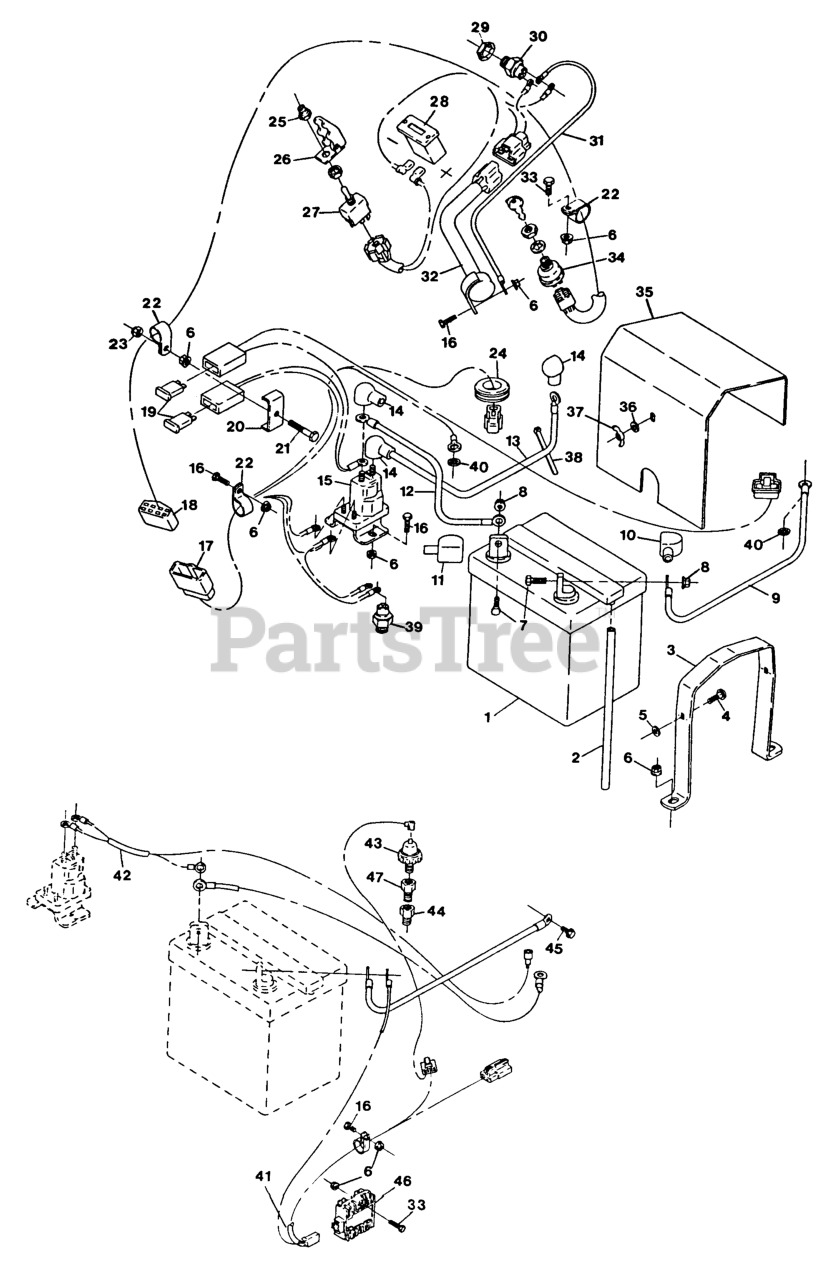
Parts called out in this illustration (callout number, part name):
1	Battery, 12v Manifold
3	STRAP,BATTERY HOLDDOWN
4	BOLT-CARR
5	NUT-RETAINING
10	INSULATOR, BATTERY -
14	INSULATOR-SOLENOID
19	FUSE-BLADE TYPE, 20 AMP
20	CLIP-FUSE BLOCK PLTD
22	CLIP-LOOM
24	GROMMET
25	BOOT-SWITCH, TOGGLE
28	METER-HOUR
30	SWITCH,OPERATOR CNTRL
37	NUT-WING
38	TIE-CABLE
39	SWITCH-START, NEUTRAL
43	SWITCH-OIL PRESSURE
45	M8 X 1.25 X 16 Mm Hh Capscrew
